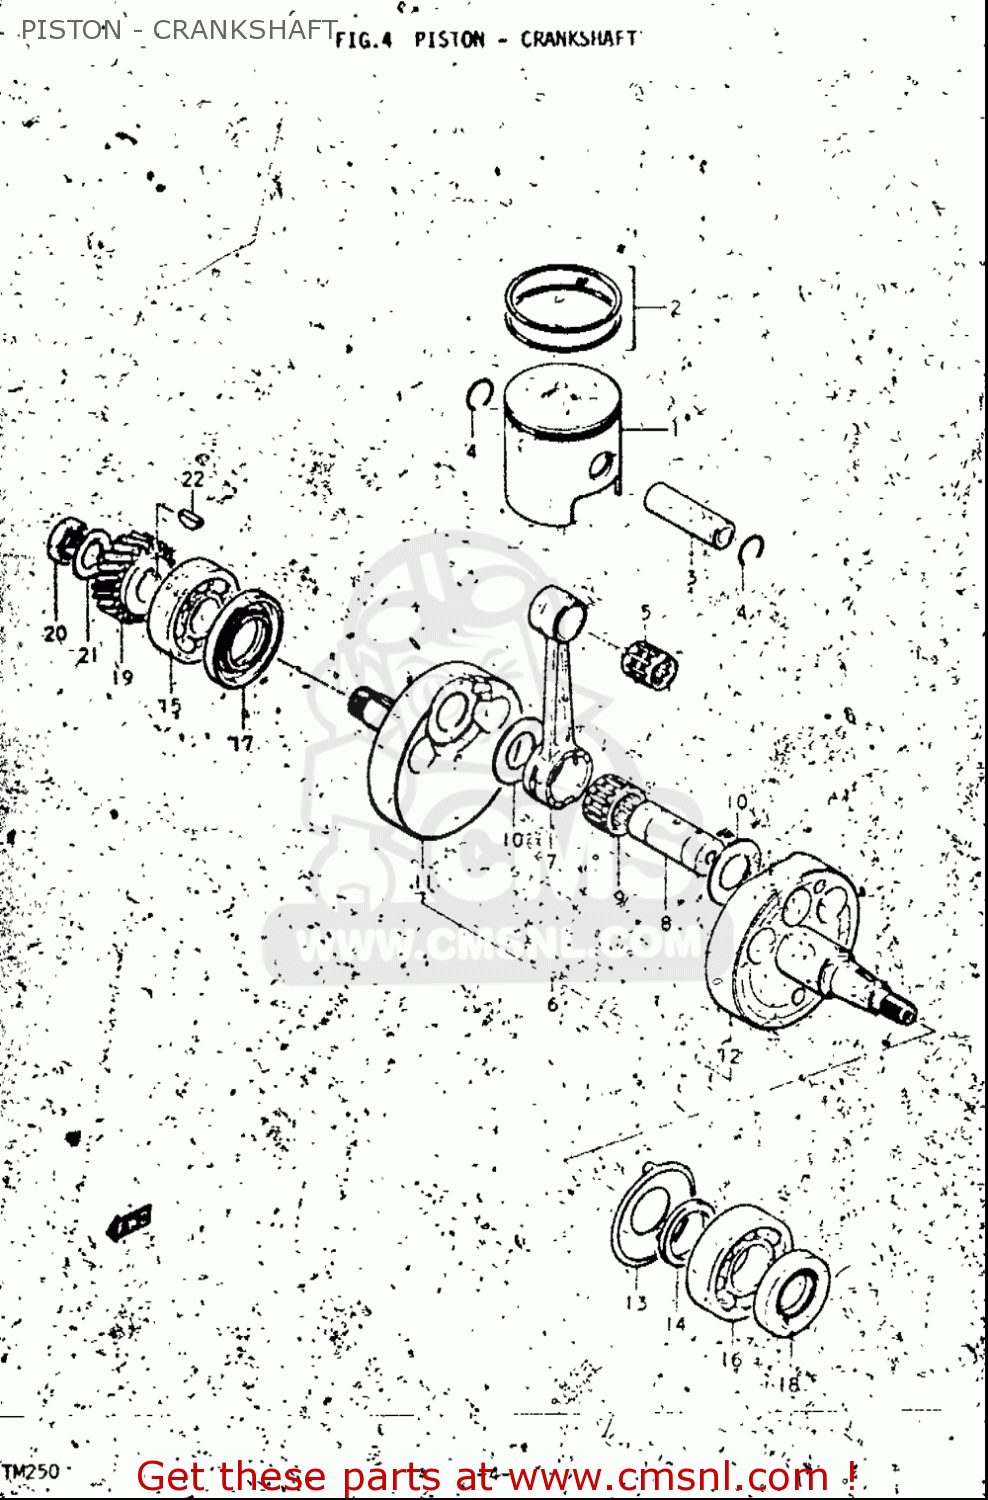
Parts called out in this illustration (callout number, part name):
2	RING SET,PISTON
3	PIN,PISTON (18MM)
4	CIRCLIP,PISTON PIN
5	BEARING(18X23X24)
7	ROD,CONNECTING
8	PIN,CRANK
9	BEARING(25X31X20)
10	WASHER(25X40X1)
15	BEARING(25X62X17)
16	BEARING(30X72X19)
17	SEAL,OIL(35X62X9)
18	OIL SEAL (30X55X10)
20	NUT
21	WASHER
22	KEY
